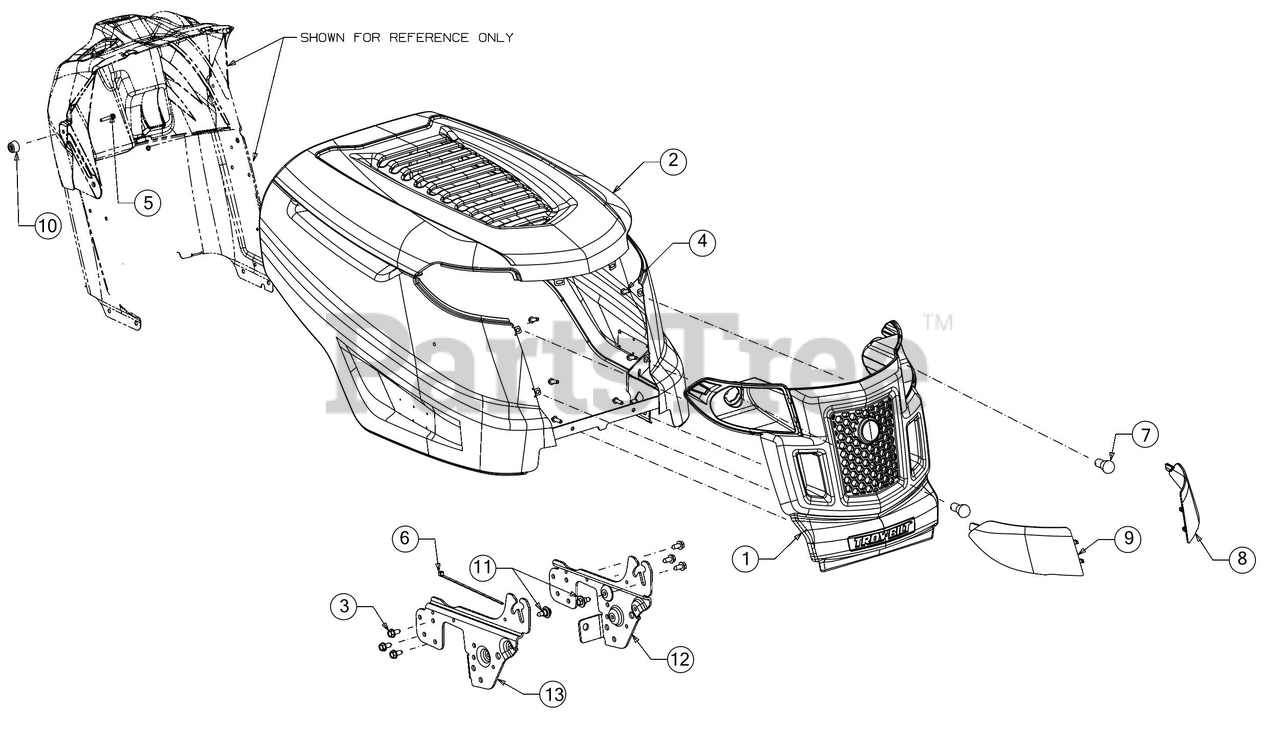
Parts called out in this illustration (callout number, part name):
1	GRILLE ASSEMBLY (TROY-BILT)
1	LABEL-TROYBILT/GEAR
2	HOOD ASSEMBLY (K STYLE)
3	SCREW 5/16-18 X .750
4	SCREW 1/4 X .750
5	SCREW #12 X 1.15
6	CABLE TIE 7"
7	MINIATUURE BULB 12V
10	DASH BUMPER K STYLE
11	SHOULDER SCREW .43X.29X5/16-18 TT
12	SUPPORT BRACKET (LH)
13	SUPPORT BRACKET (RH)
